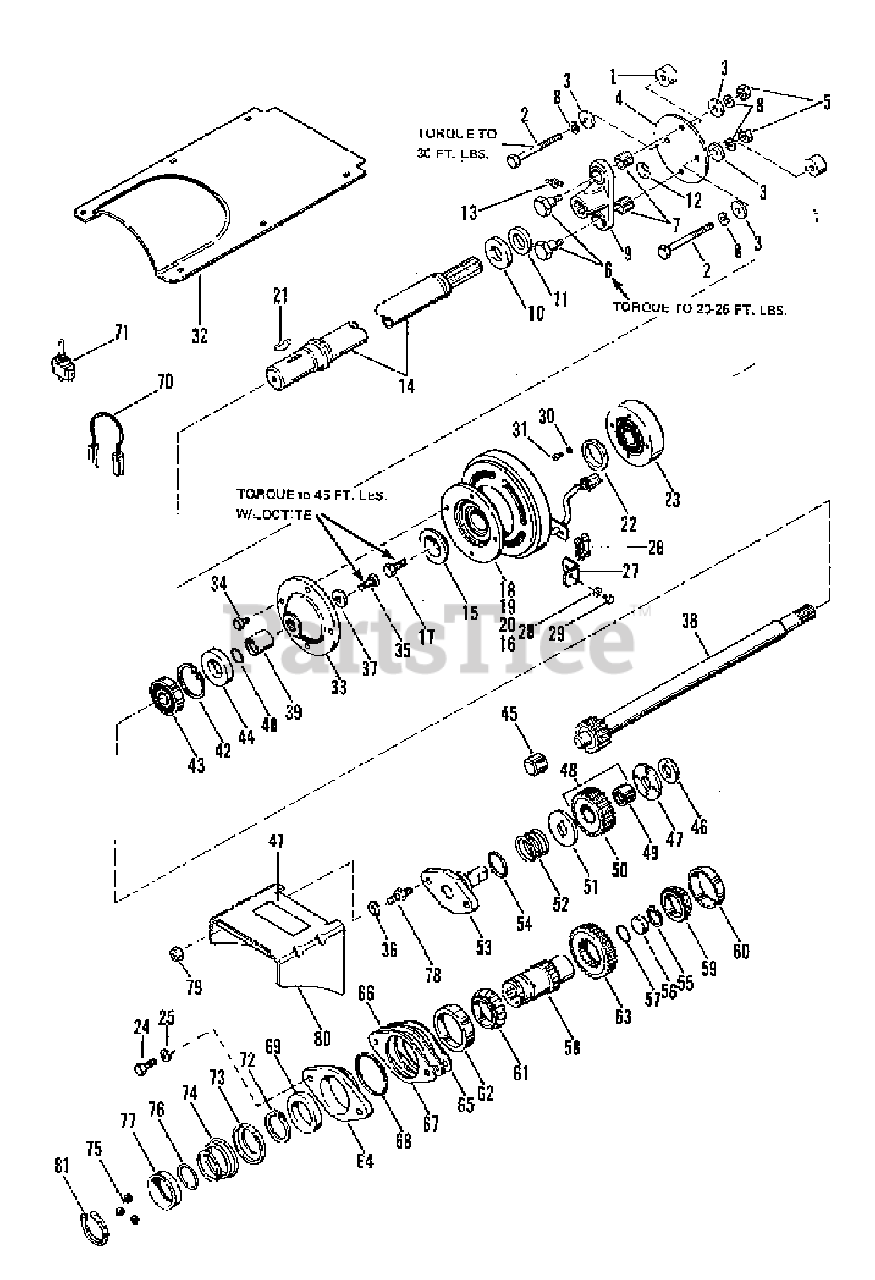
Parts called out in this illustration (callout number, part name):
2	CAPSCREW, Hex, 3/8"-16 x 3-1/2"
3	WASHER, Special
5	NUT, Hex, Jam, 3/8"-16
6	BOLT, Shoulder
8	LOCKWASHER, 3/8"
11	WASHER, Felt
13	FITTING, Grease
14	SHAFT ASSEMBLY
17	CAPSCREW, Hex, Whiz Lock, 3/8"-16 x 1-1/4" LG
18	CLUTCH, Electric
19	FIELD ASSEMBLY
20	ROTOR ARMATURE ASSEMBLY
23	BEARING, Assembled
24	CAPSCREW, Hex, 3/8-16 x 1
25	LOCKWASHER, 3/8
26	LINK, Connector
27	BRACKET ASSEMBLY
28	LOCKWASHER, 1/4"
29	CAPSCREW, Hex, 1/4"-20 x 3/4" Lg
30	LOCKWASHER, No. 10
31	SCREW, Socket Head, No. 10-32 x 1/2" Lg
32	COVER, Top
34	CAPSCREW, Hex, 5/16"-18 x 1" Lg
35	CAPSCREW, Hex, Whiz Lock, 3/8"-16 x 1" Lg
36	LOCKWASHER, 3/8"
37	WASHER, Special
38	P.T.O. SHAFT ASSEMBLY
41	FILM, Safety
42	RING, Retaining
43	BEARING, Ball
44	SEAL, Brake
47	WASHER, Thrust
48	GEAR ASSEMBLY
49	BEARING
51	WASHER, Thrust
53	CAP ASSEMBLY
55	RING, Retaining
58	SHAFT, Drive
59	CONE, Bearing
60	CUP, Bearing
61	CONE, Bearing
62	CUP, Bearing
65	SHIM, .002
66	SHIM, .010
67	SHIM, .003
70	WIRE, Jumper
71	SWITCH, Electric
72	RING, Retaining
76	RETAINER, Spring
79	NUT, Full Hex, 3/8"-16
81	RING, Retaining
